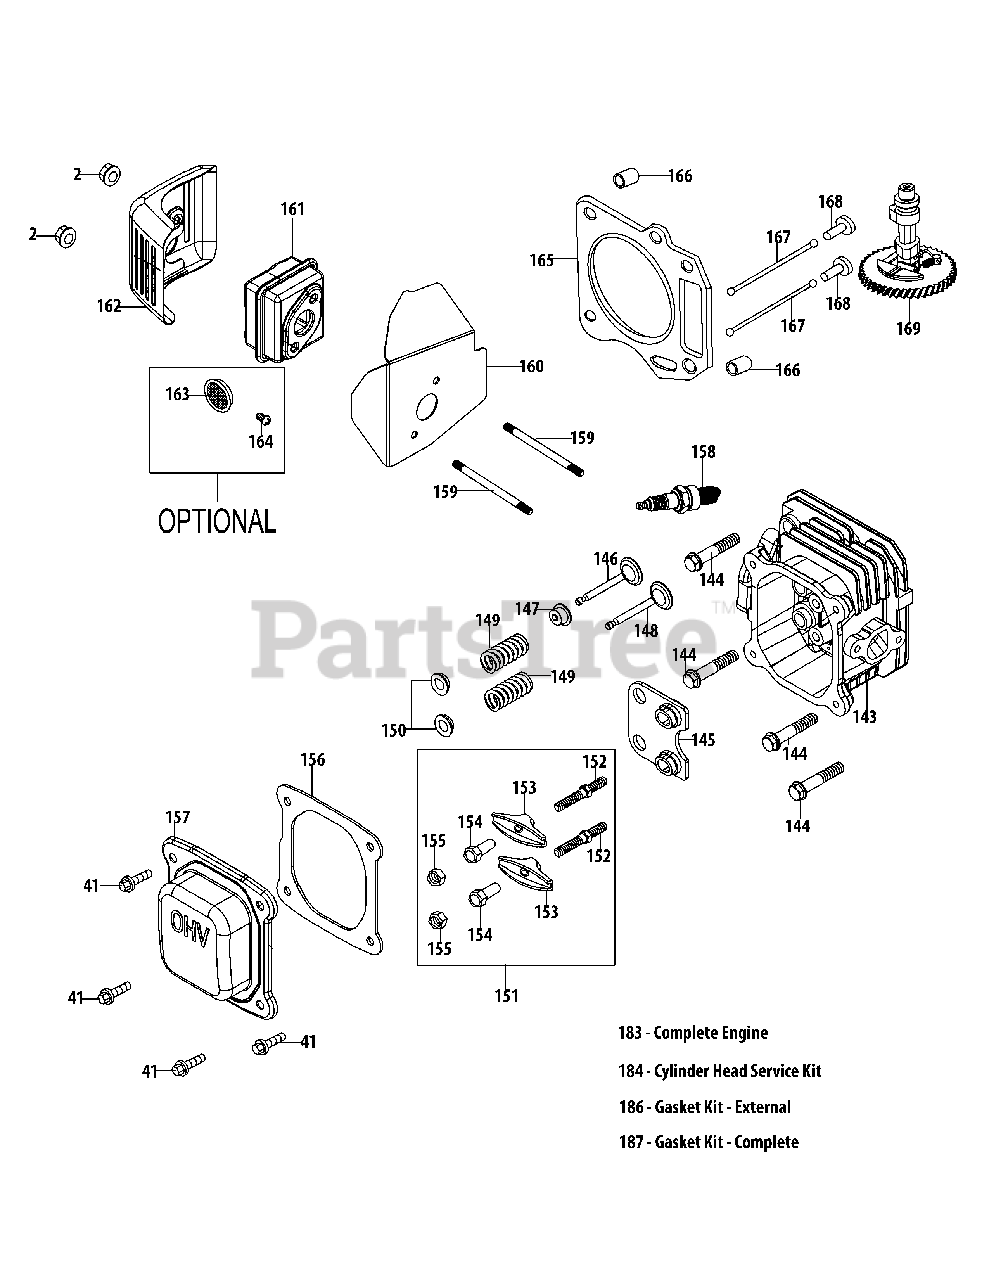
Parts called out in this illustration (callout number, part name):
2	Nut M6X10M
41	Bolt M6X14 Multi-Purpose
143	Cylinder Head
144	Bolt M8X54 Cylinder Head
145	Push Rod Guide
146	Valve Kit
147	Intake Valve Seal
148	Valve Kit
149	Valve Spring
150	Valve Spring Retainer
151	Rocker Arm Assembly
152	Rocker Arm Stud
153	Rocker Arm
154	Fulcrum Nut
155	Jam Nut
156	Valve Cover Gasket
157	Valve Cover
158	Spark Plug
159	Muffler Stud M6X68
159	Muffler Stud Assy
160	Muffler Gasket
161	Muffler Assembly
162	Muffler Shield
163	Spark Arrestor
164	Spark Arrestor Screw
165	Cylinder Head Gasket
166	Cylinder Head Dowel Pin 10×16
167	Push Rod
168	Tappet
169	Camshaft Assembly
183	Complete Engine
184	Cylinder Head Svc Kit
186	Gasket Kit - External
187	Gasket Kit - Complete
